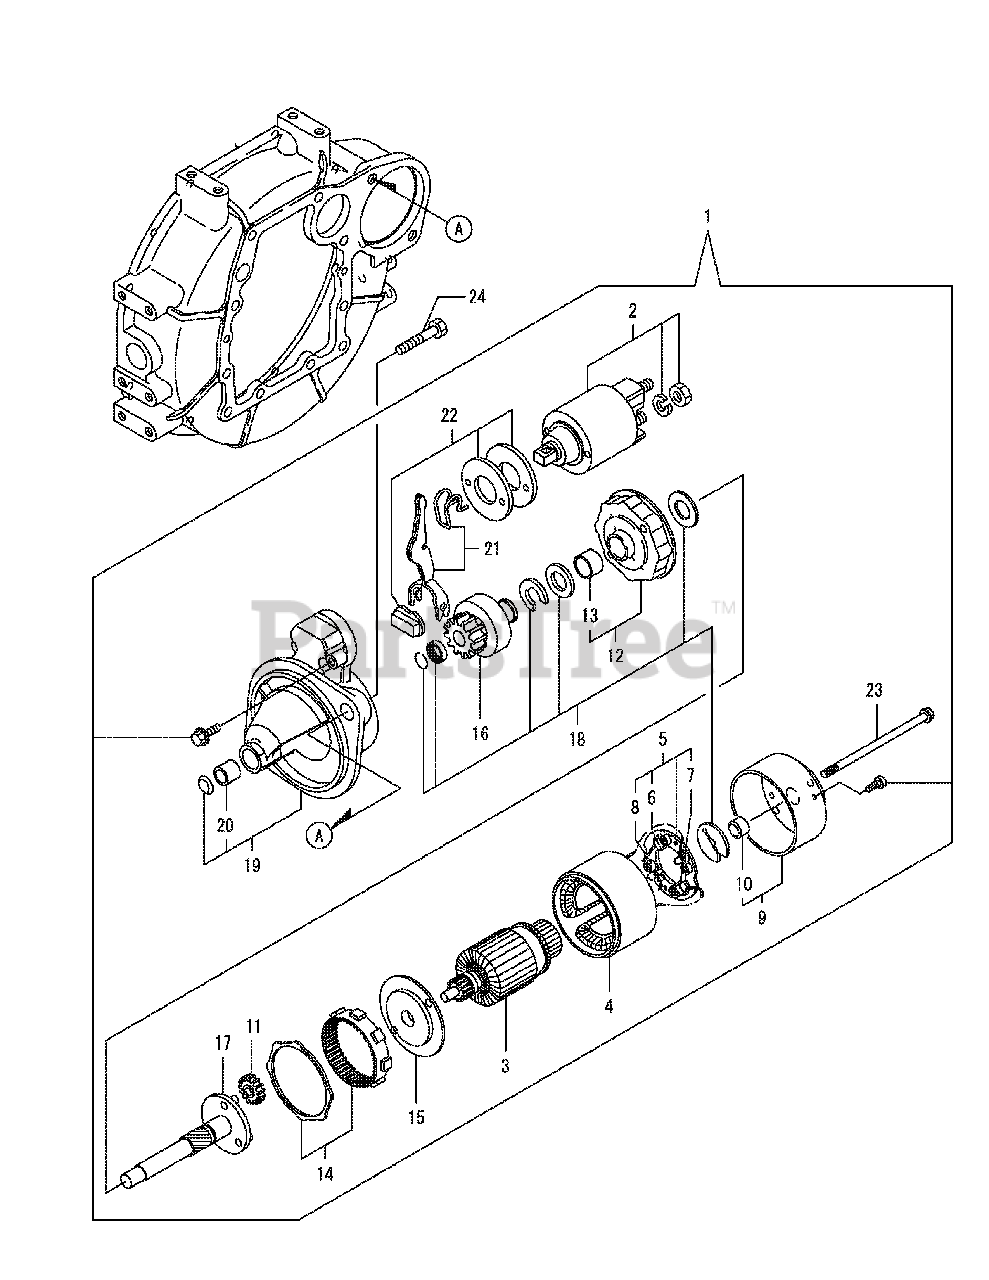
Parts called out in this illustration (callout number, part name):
2	Magnetic Switch Assembly
3	Armature Assembly
5	Brush Holder Assembly
9	Rear Cover Assembly
10	Rear Cover Metal
12	Center Bracket (P)
15	Center Bracket (A)
16	Pinion Assembly
17	Shaft (Pinion)
19	Gear Case Assembly
20	Starter Metal
21	Shift Lever Set
22	Dust Cover Kit
23	Through Bolt
24	Bolt, M12 x 20
